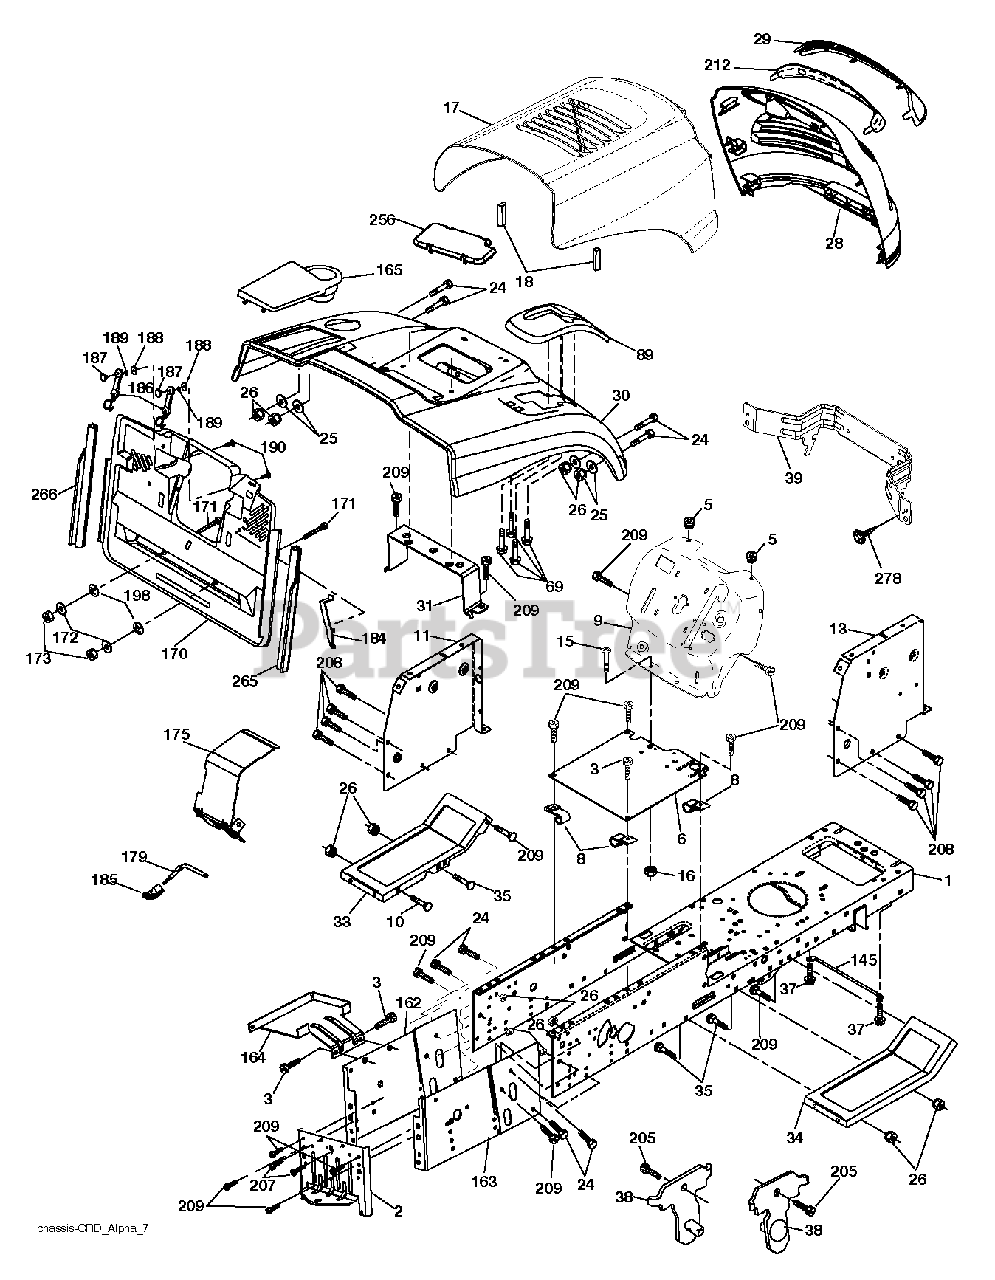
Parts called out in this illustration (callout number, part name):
1	CHASSIS
3	SCREW 3/8-16X3/4
5	BUMPER.RUBBER.HOOD
8	CLIP,INSULATOR
9	FENDER LT SH
10	BOLT D
11	PANEL.DASH.LH.LTX
13	PANEL DASH RH
16	NUT
17	HOOD.PNT.STEEL.ALPHA.LT.667
18	BUMPER.HOOD.LARGE.1.75"
25	WASHER
26	NUT
28	GRILLE.ASM.ALPHA
29	LENS.ALPHA.BAR.LT
30	FENDER.PNT.CRD.MS667
31	BRACKET SUPPORT FENDER
33	FOOTREST.PNT.LH.MS667
34	FOOTREST.PNT.RH.MS667
39	BRACKET.PIVOT.ALPHA.LT
69	SCREW.HI-LO.CONSOLE
89	CONSOLE.CRD.AUTO.BLACK
145	ROD.PIVOT.HOOD
164	SUPPORT
165	FENDER.PNT.CRD.
171	BOLT
172	WASHER
184	BRACKET.ACTUATOR.BAGGER.SRD
185	KNOB.BRAKE.PARKING.ROD
187	WELDNUT
207	SCREW, 5/16-18 X 1/2
208	SCREW 3/8-16X1/2
209	SCREW, 3/8-16X3/4
212	INSERT.ALPHA.REFLECTIVE.LT.
256	FENDER.PNT.CRD
278	SCREW.#10 X 0.750.BOS THREAD
